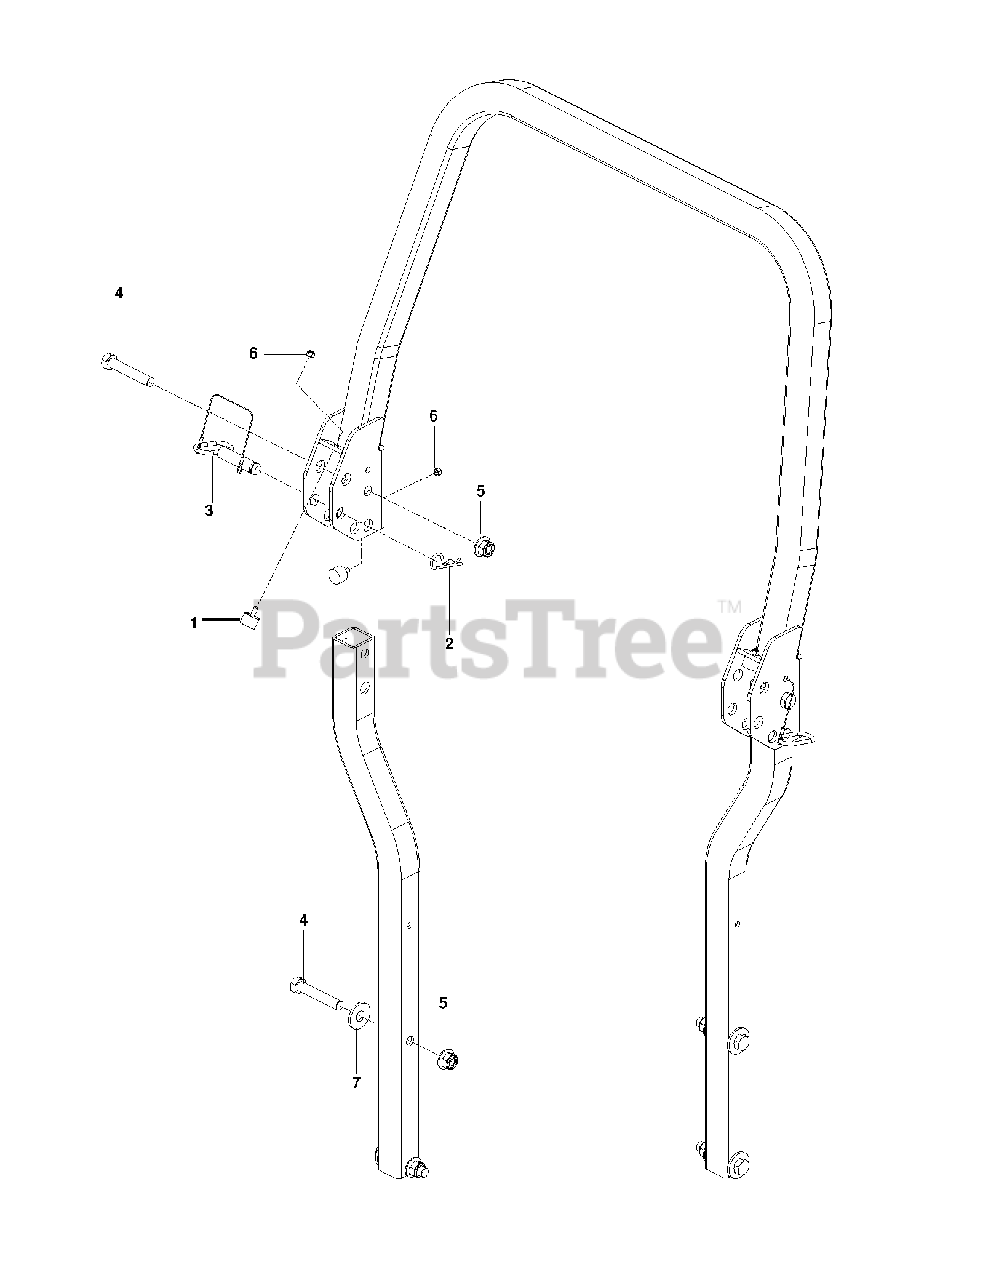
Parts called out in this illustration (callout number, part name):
1	BUMPER, MALE STUD, 1/4-20
2	PIN HAIR .148 X 2-15/16 #210
3	PIN, ROPS
4	5/8-11 X 3-1/2 HHB GRADE 5
5	NUT 5/8-11 FLG NYLOC ZD
6	NUT 1/4-20 NYLOC
7	WASHER, 5/8 FLAT
